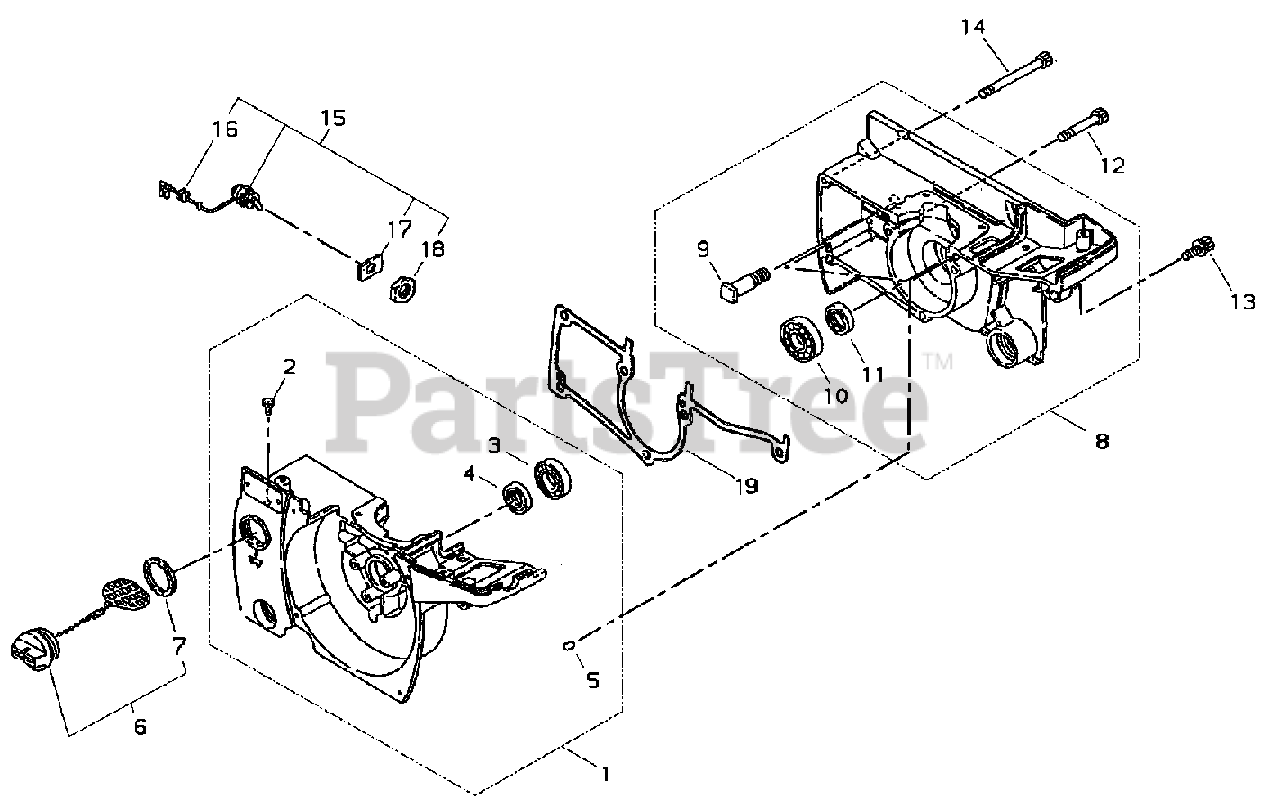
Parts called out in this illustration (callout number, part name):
1	CRANKCASE ASSY, M
2	VENT ASSY
3	BEARING, BALL 6001 C3
4	SEAL, OIL 12
5	PIN, LOCATING 4×8
6	CAP ASSY, OIL
7	GASKET, CAP
8	CRANKCASE ASSY, C
9	STUD, GUIDE BAR
10	BEARING, BALL 6201 C3
11	SEAL, OIL 12
12	BOLT, ADHESIVE M5×30
13	BOLT, ADHESIVE M5×18
14	BOLT, ADHESIVE M5×45
15	SWITCH ASSY, ON-OFF
16	GROMMET
17	PLATE, SWITCH
18	NUT 10
19	GASKET, CRANKCASE
